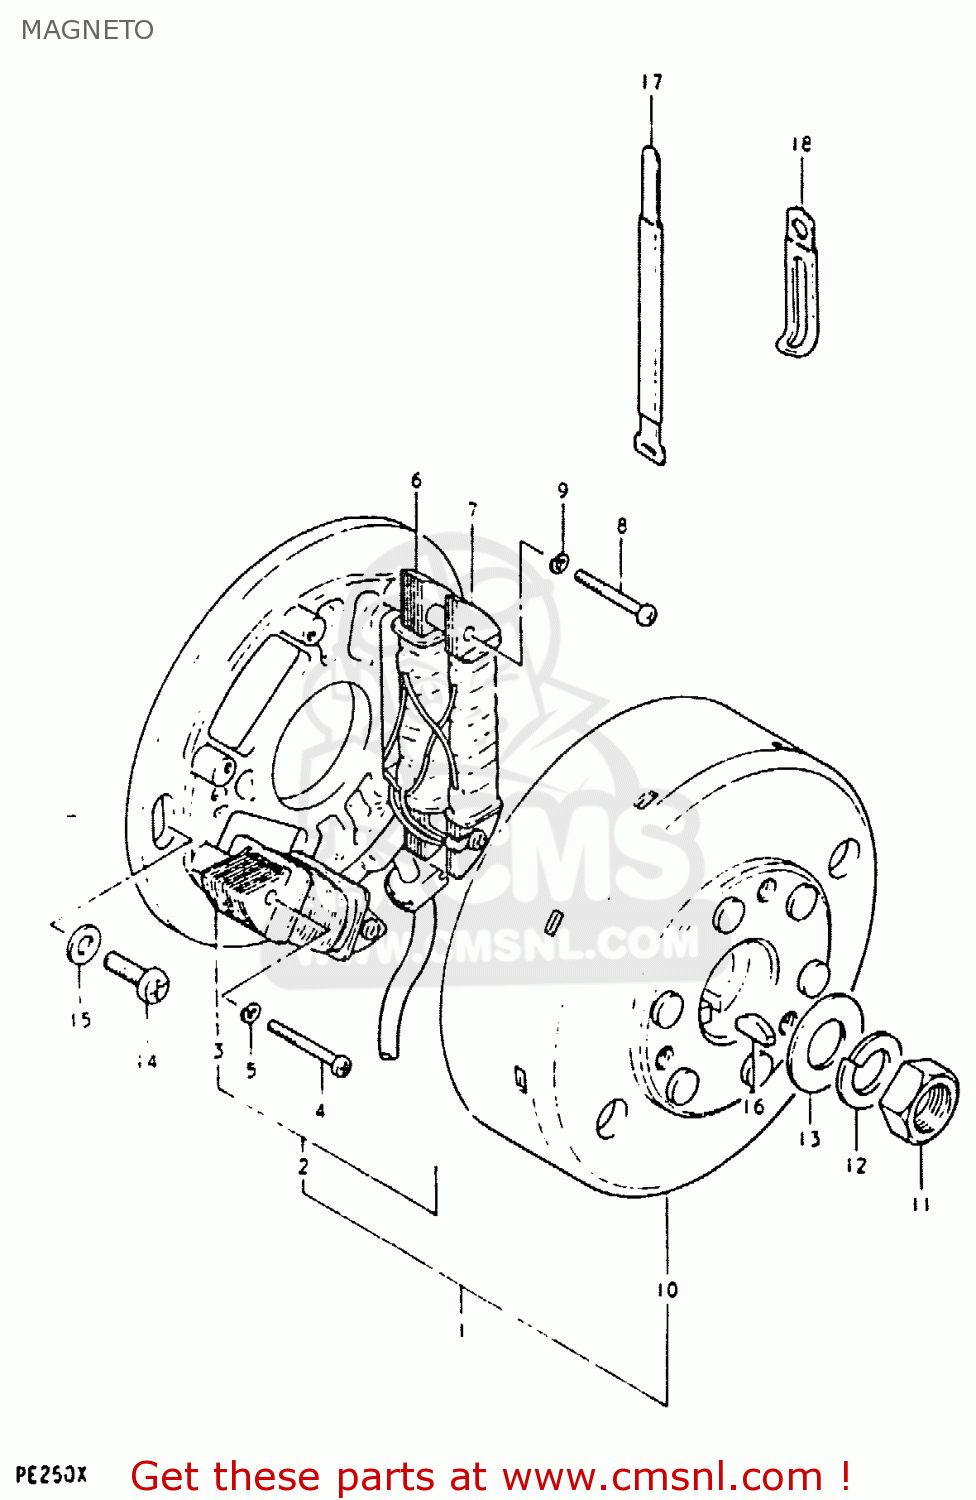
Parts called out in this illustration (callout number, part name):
1	MAGNETO ASSEMBLY
2	STATOR ASSEMBLY
3	COIL,LIGHTING
4	SCREW (4X30)
5	LOCK WASHER
6	COIL,PRIMARY
7	COIL,PULSER
8	SCREW
9	LOCK WASHER
10	ROTOR ASSEMBLY
11	NUT (10MM)
12	LOCK WASHER
13	WASHER
14	SCREW
15	WASHER
16	KEY 4MM
17	CLAMP L:110
18	CLAMP
